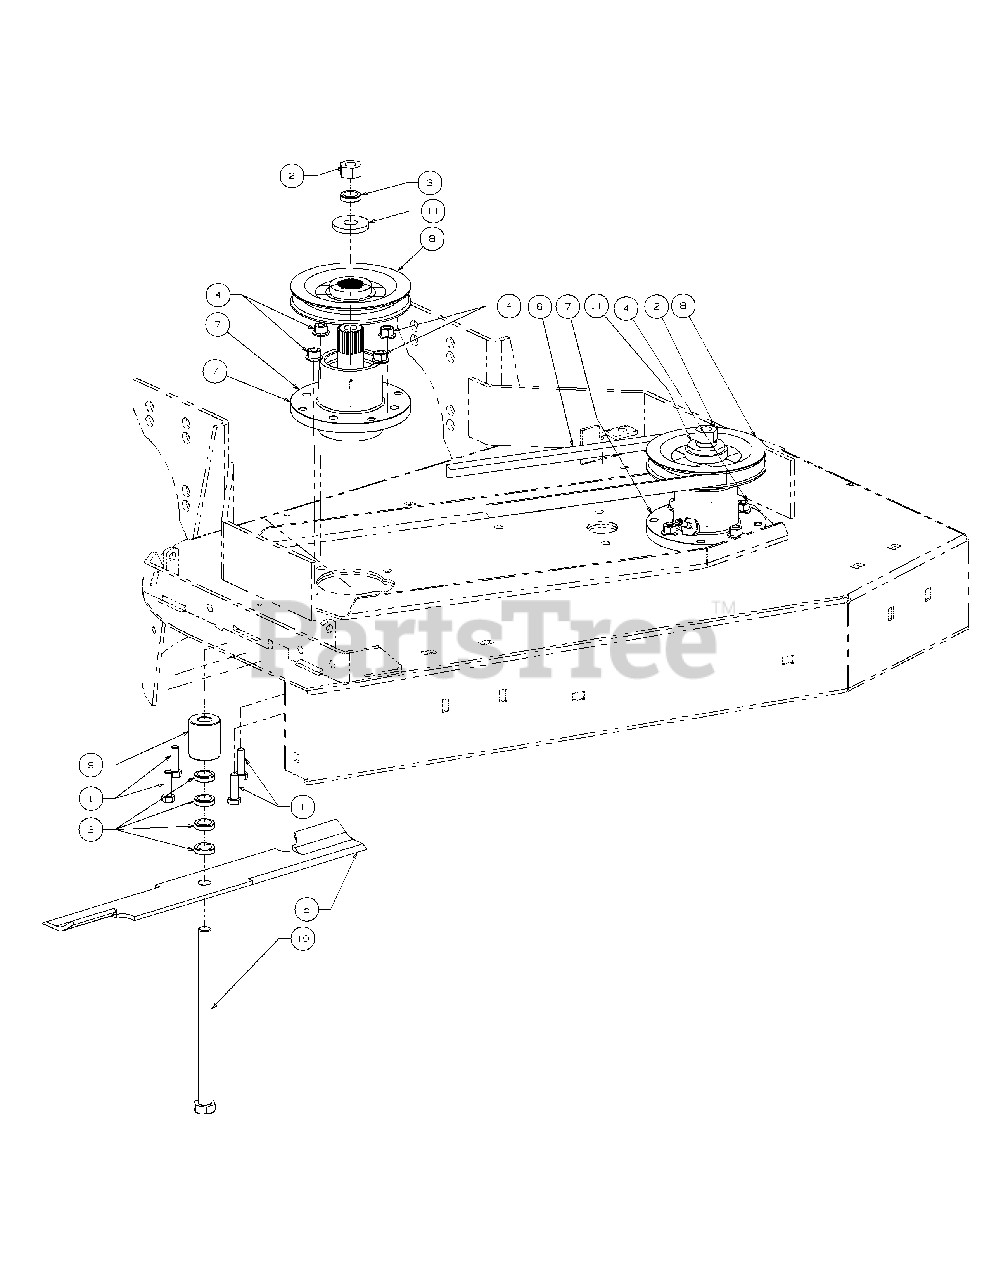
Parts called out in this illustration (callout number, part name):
1	Hex Cap Screw, 3/8-16 x 1-1/2
2	Hex Nut, 5/8-11
3	Blade Spacer, 5/8 ID, 1/4 Thick
4	Hex Nut Flange Lock, 3/8-16
5	18" Rotary Blade
6	V-Belt
7	Spindle Assembly
7	Grease Fitting, 1/4-28 x 1.609
8	Deck Pulley
9	Blade Spacer, .630 x 1.500 x 1.850
10	Hex Cap Screw, 5/8-11 x 9
11	Flat Washer, .656 ID x 1.313 OD
